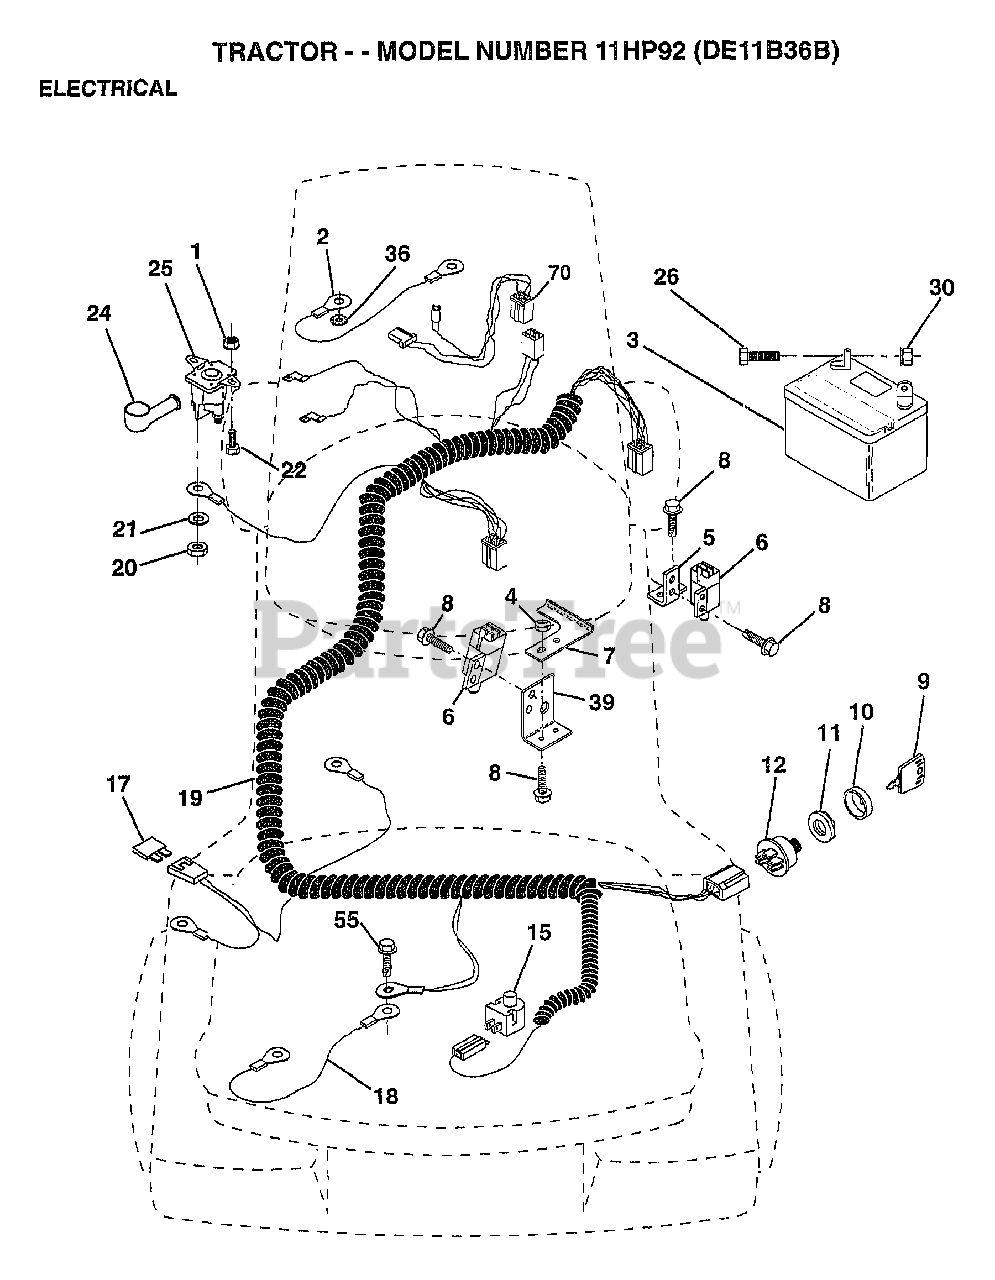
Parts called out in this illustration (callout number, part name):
1	NUT HXKEP 1/4X20
2	CABLE ASM.
4	LOCKNUT
5	BRACKET LT
6	SWITCH INTERLOCKT
7	KEEPER.ACTUAT.LR.
8	SCREW
9	KEY STEEL DELTA
10	COVER KEY SWITCH
12	SWITCH.IGNITION
15	SWITCH SEAT
17	FUSE HYT
18	CABLE ASSY
19	HARNESS.IGNITION
20	NUT
22	BOLT HXHD FIN
26	BOLT LT
27	NUT
36	LOCKWASHER
39	BRACKET SWT CLUTC
55	SCREW LT
70	HARNESS, ENGINE
